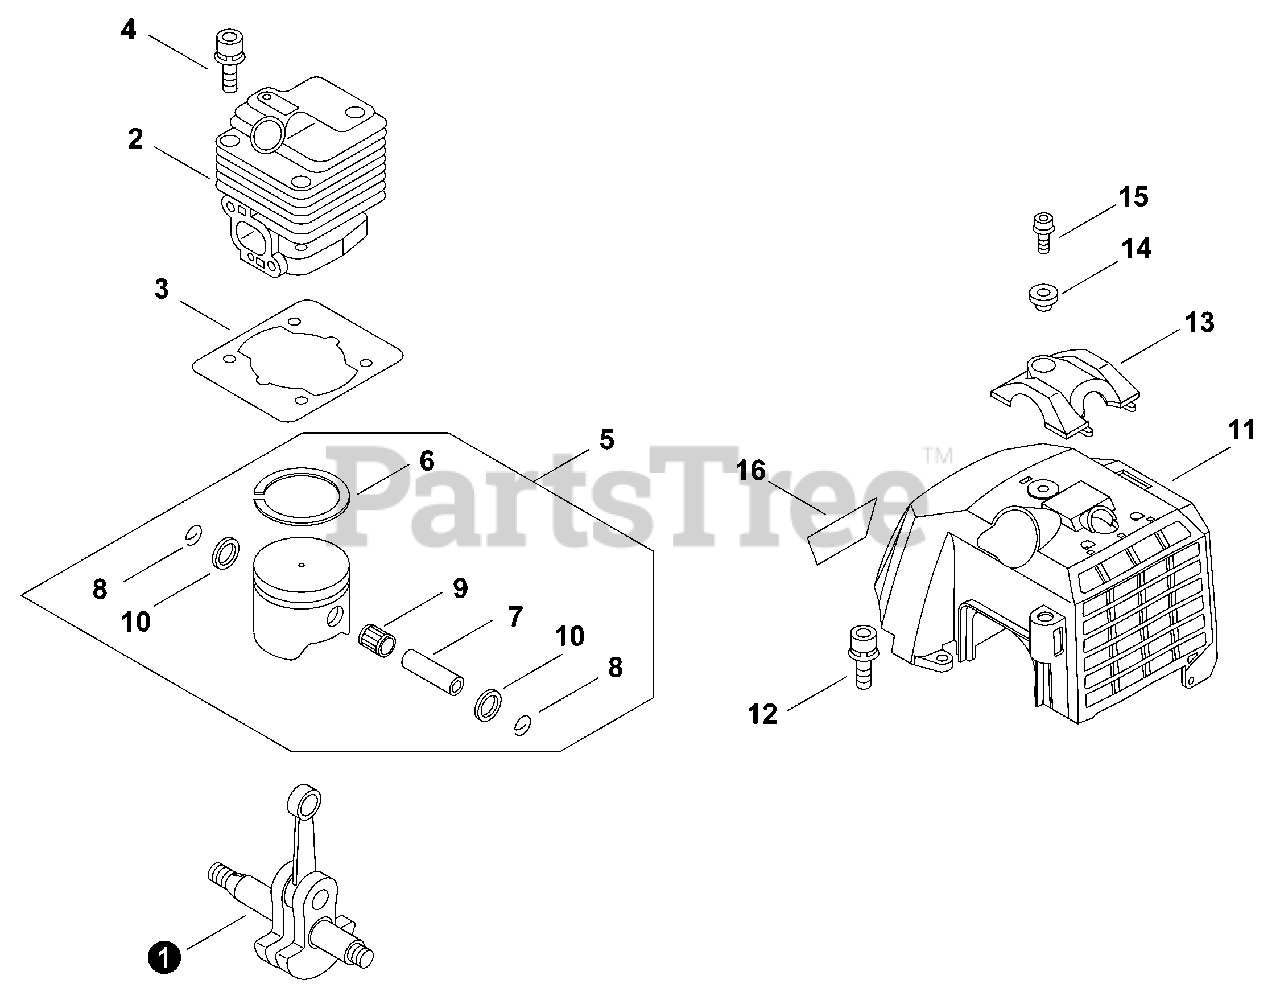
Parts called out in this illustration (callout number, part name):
1	CRANKSHAFT ASSY
2	CYLINDER
3	GASKET, CYLINDER
4	BOLT 5×20
5	PISTON KIT
6	RING, PISTON
7	PIN, PISTON 10
8	RING, SNAP 10
9	BEARING, NEEDLE 10
11	COVER, ENGINE
12	BOLT 5×12
13	GUARD, TOP
14	COLLAR 5
15	BOLT 5×20
16	LABEL - MODEL RM-4300
